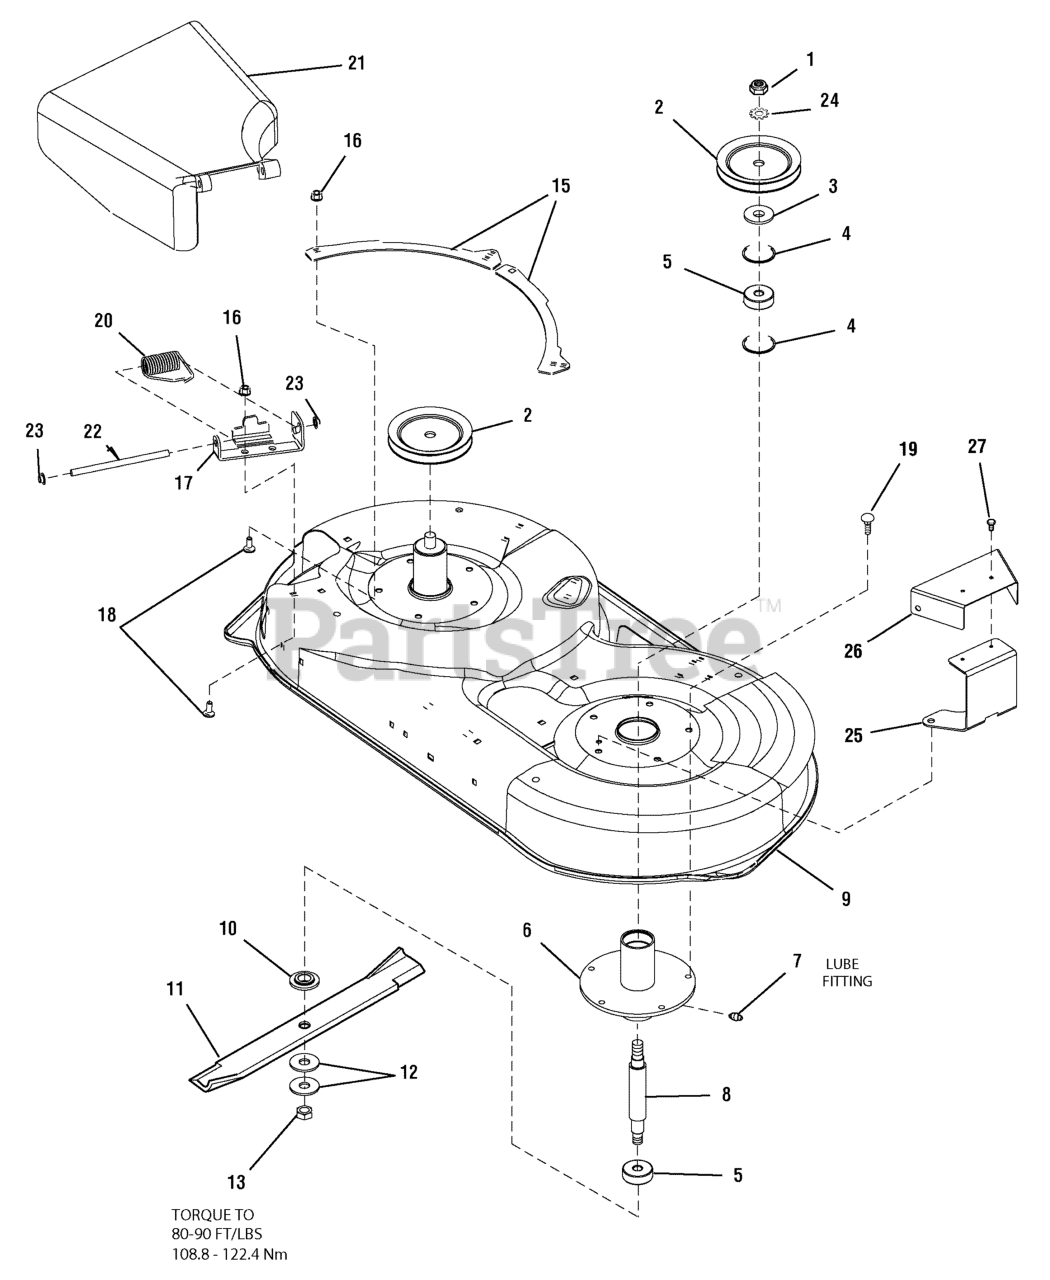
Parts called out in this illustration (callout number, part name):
1	NUT, Hex Jam, 5/8-18
2	PULLEY, 5.5"
3	SPACER, Pulley
4	RETAINING RING, External 1-3/4
5	BEARING, Ball
6	TUBE & PLATE ASSEMBLY, Spindle
7	LUBE FITTING, 1/4 Drive w/Check Ball
8	SHAFT, Spindle
9	HOUSING, 42"
10	WASHER, Spindle Blade, Powdered Metal
11	BLADE, Mower 42"
12	WASHER, Belleville, 1-3/4
13	NUT, Hex, 9/16
15	PLATE, Rear 42"
16	NUT, Hex Flange Whiz Lock, 5/16-18
17	BRACKET, Hinge
18	CARRIAGE BOLT, 5/1-18 x 3/4, G5
19	CAPSCREW, Hex Washer Head Taptite, 3/8-16 x 3/4
20	SPRING, Torsion
21	DEFLECTOR & SUPPORT ASSEMBLY, Chute Riveted
22	ROD, Deflector
23	NUT, Push Pal 3/8
24	LOCKWASHER, Interior Tooth 5/8
25	SUPPORT, Pulley Cover
26	COVER, Pulley
27	SCREW, Taptite 1/4-20 x 1/2
